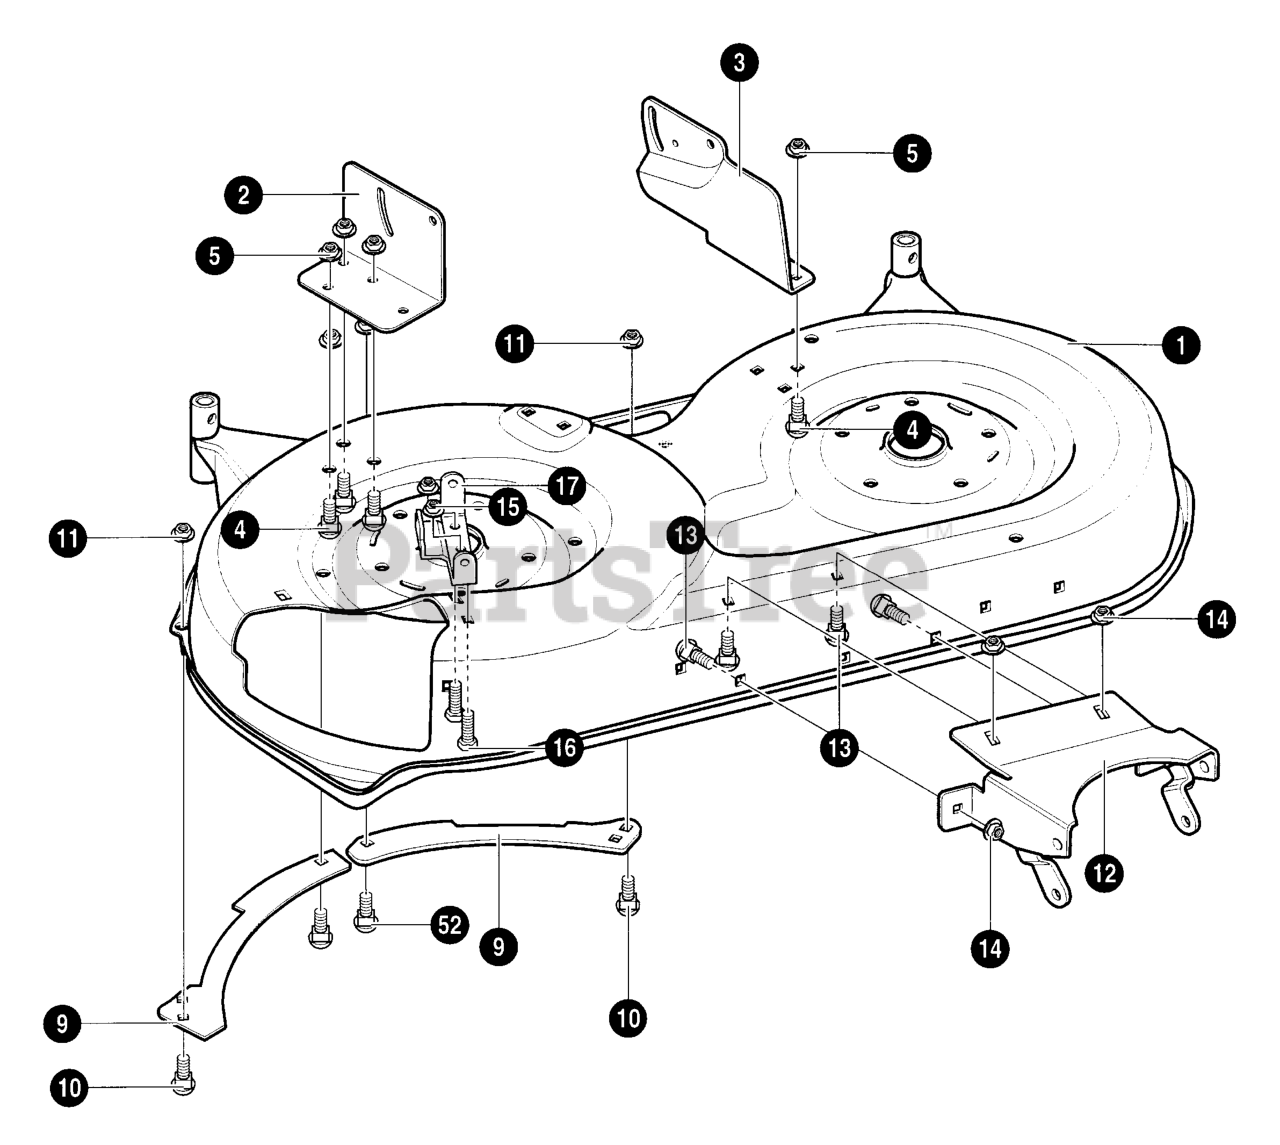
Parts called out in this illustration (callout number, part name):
1	ASSY BLD HSING 42"
2	BRACKET, DECK RH
3	BRACKET, DECK LH
4	BOLT, 5/16- 18X.63
5	NUT, 5/16- 18
9	TOEGUARD, FLANGE
10	BOLT, 5/16- 18X.63
11	NUT, 5/16- 18
12	ASSY FRONT BRACKET ROLLER
13	BOLT, 5/16- 18X.63
14	NUT, 5/16- 18
15	BRACKET, CHUTE
16	BOLT, 5/16- 18X.63
17	NUT, 5/16- 18
